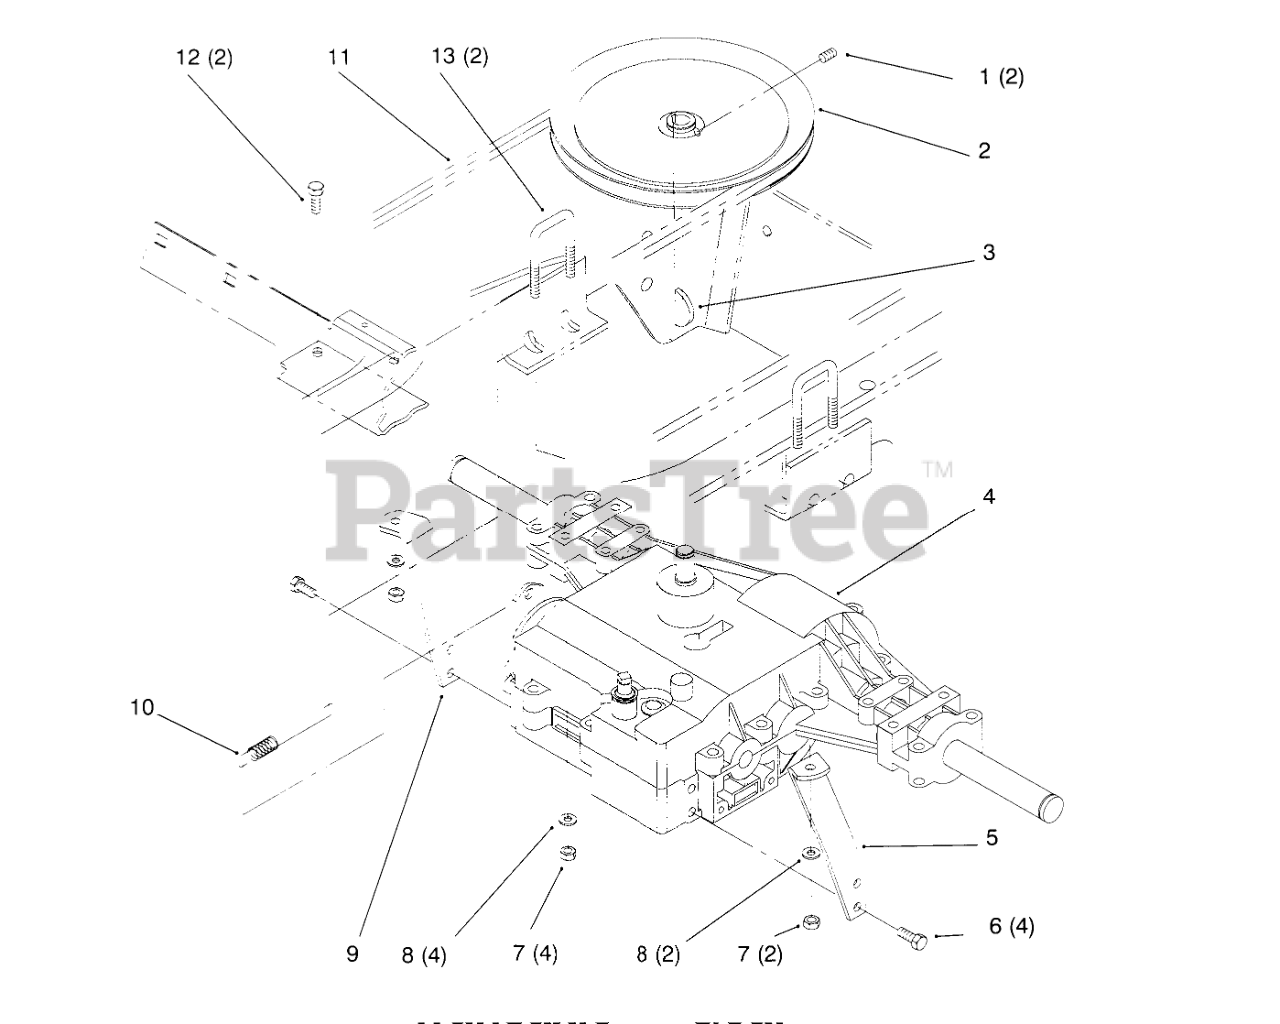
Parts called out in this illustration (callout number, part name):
1	Screw-Set (Only On: 72042,72062)
2	Pulley (Only On: 72042,72062)
3	Key (Only On: 72042,72062)
4	Transaxle-Peerless 820 (Only On: 72042,72062)
5	Strap-Torque LH (Only On: 72042,72062)
6	Screw-TAP (Only On: 72042,72062)
7	Nut-Lock (Only On: 72042,72062)
8	Washer-Flat (Only On: 72042,72062)
9	Strap-Torque RH (Only On: 72042,72062)
10	Spring-Extension (Only On: 72042,72062)
11	Belt-Gear (Only On: 72042,72062)
12	Screw-HH (Only On: 72042,72062)
13	U-Bolt (Only On: 72042,72062)
